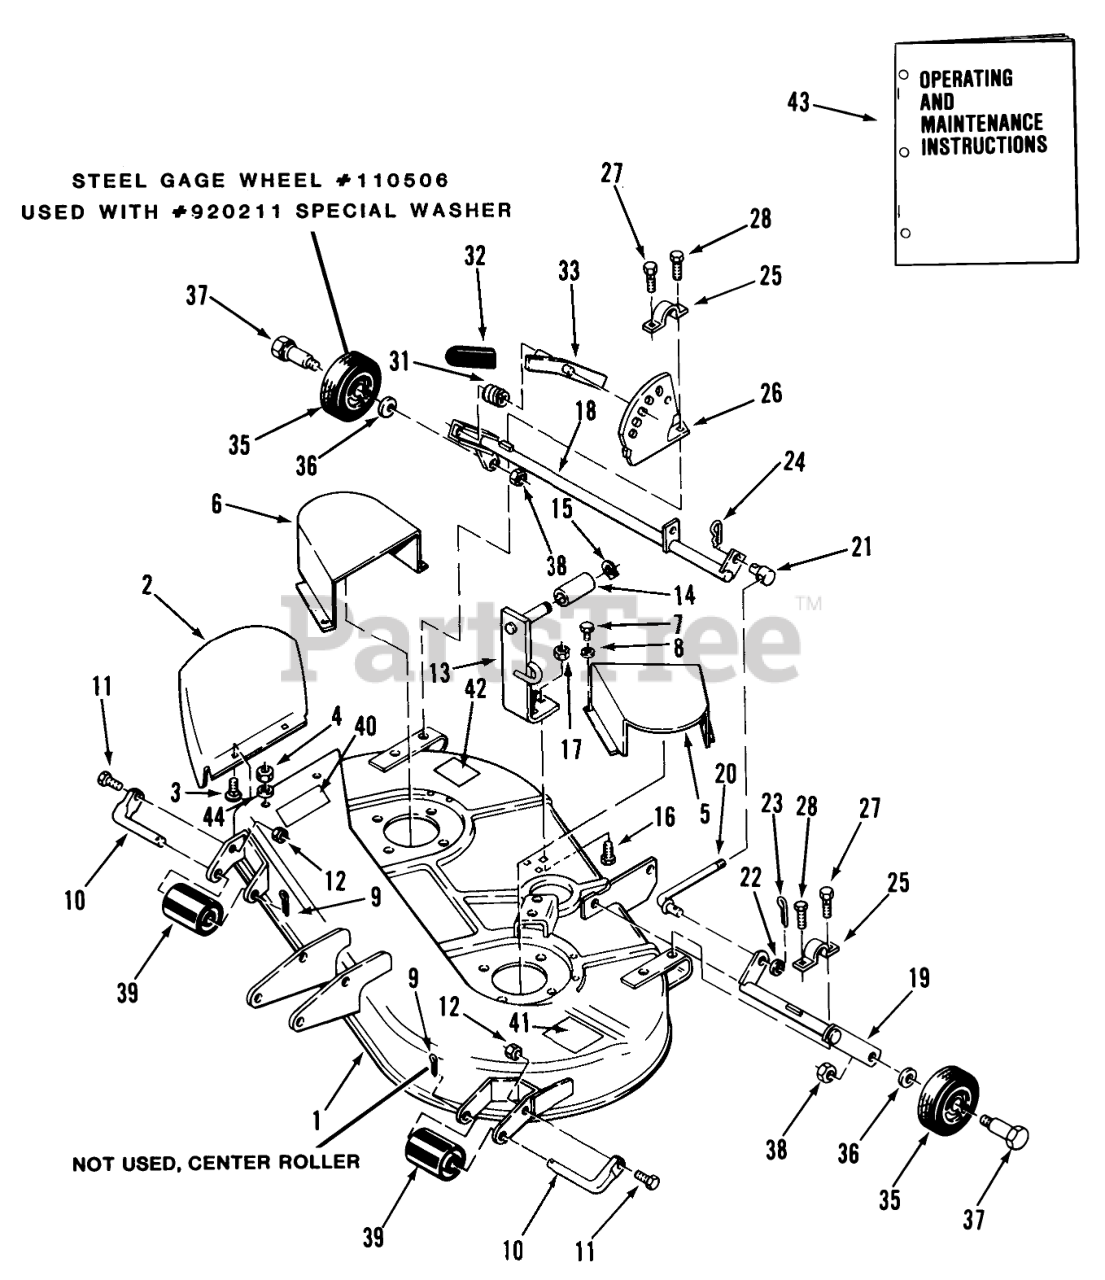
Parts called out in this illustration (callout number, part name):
1	Mower Deck
2	Chute Extension
3	CARRIAGE BOLT -4
4	Nut
5	COVER R
6	COVER R
7	Bolt
8	WASHER
9	Cotter Pin
10	Roller Shaft
11	H H C S
12	Nut
13	BRACKET ASSY R
14	SPACER
15	Snap Ring
16	BOLT HEX SPECIAL
17	Nut
18	Gage Wheel Support RH
19	WA GAG WHL R
20	Rod
21	TRUNNION
22	Washer
23	Pop Rivet
24	Hairpin
25	CLAMP
26	Quadrant
27	Bolt
28	Bolt
31	SPRING-COMPRESSION
33	Lever
35	Wheel 6 x 1.75
36	WASHER
37	BOLT-SHOULDER
38	Nut
39	Roller
40	DECAL
41	Caution Decal
42	DECAL-BELT&HEIGHT
43	Operating & Maintenance Instructions
44	WASHER 5/16 SAE
